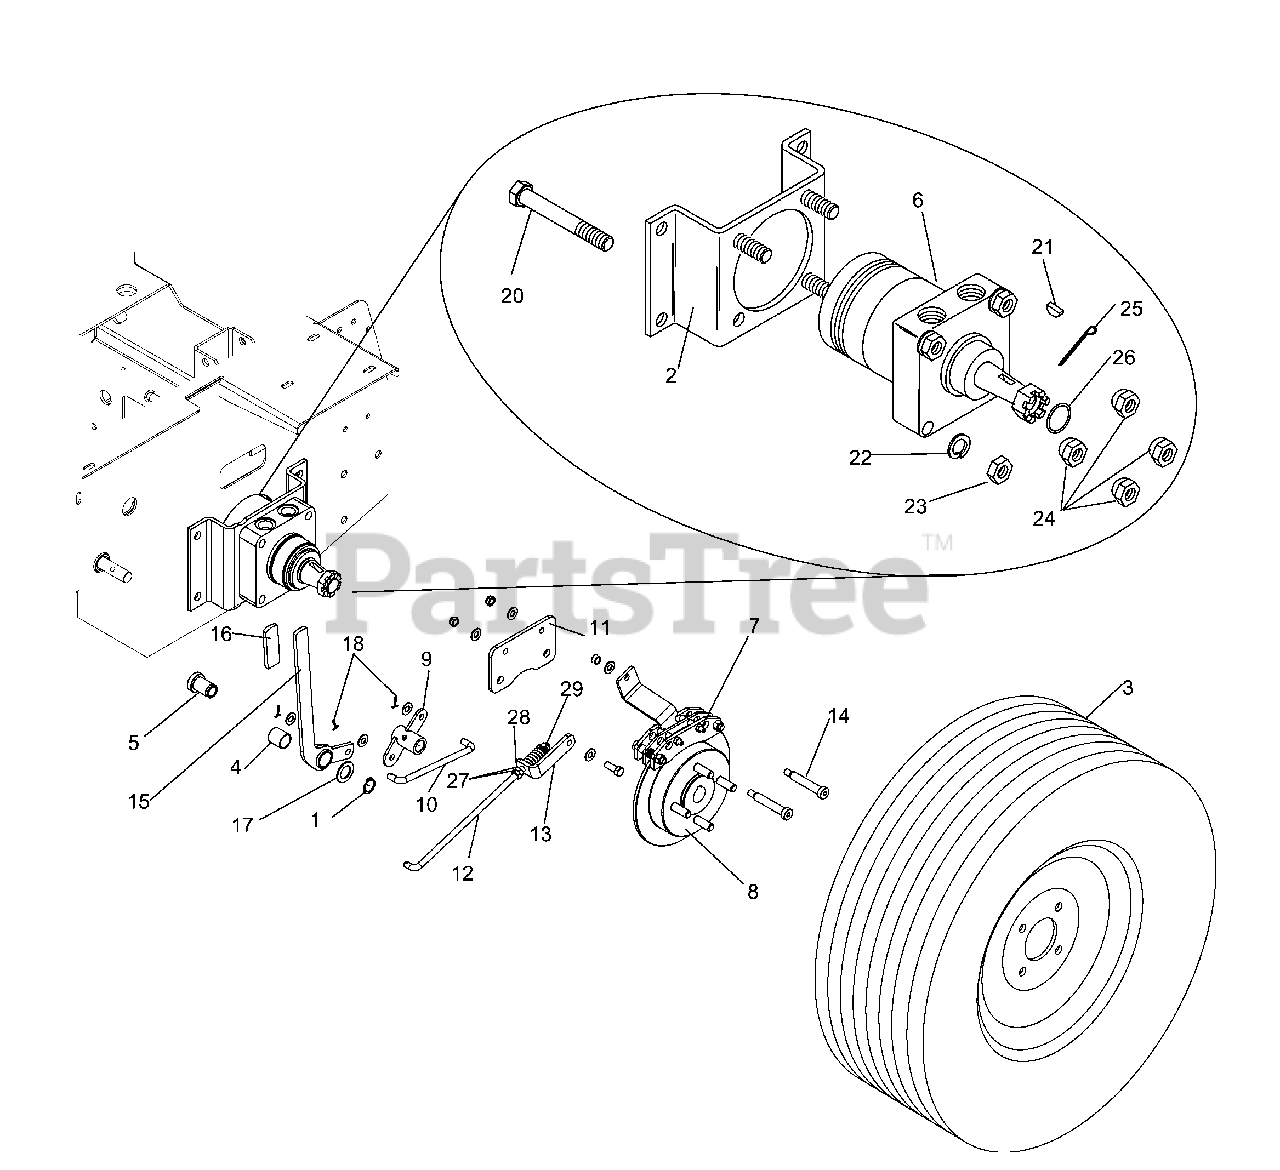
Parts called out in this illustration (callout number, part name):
1	RETAINING RING, 7/8"
2	MOTOR STANDOFF - PAINTED
3	TIRE ASSY 24-12
4	BUSHING
5	TUBE LT, SIDE
6	TL15 WHEEL MOTOR
7	CALIPER ASSEMBLY
9	BELLCRANK, BRAKE
10	LINKAGE, BRAKE
11	PLATE, BRAKE
12	LINKAGE, REAR BRAKE
13	BRACKET, L
14	SB 3/8-16 X 2-1-1/2 SKT HDD ZD
15	LEVER, BRAKE WELDMENT
16	GRIP BRAKE HANDLE
17	BSHG .875 X 1.375 X .074 ZD
18	COTTER PIN 3/32 X 3/4
20	HCS 1/2C X 2 3/4
21	ZERK
22	WASHER 1/2" SPLIT LOCK
23	NUT HEX 1/2
24	LUG NUT 1/2F
25	PIN COTTER 4MM X 45MM
26	MACHINE BUSHING
27	NUT 3/8-24 JAM
28	WASHER 3/8 SAE FLAT
29	NUT 3/8F CENTERLOCK
